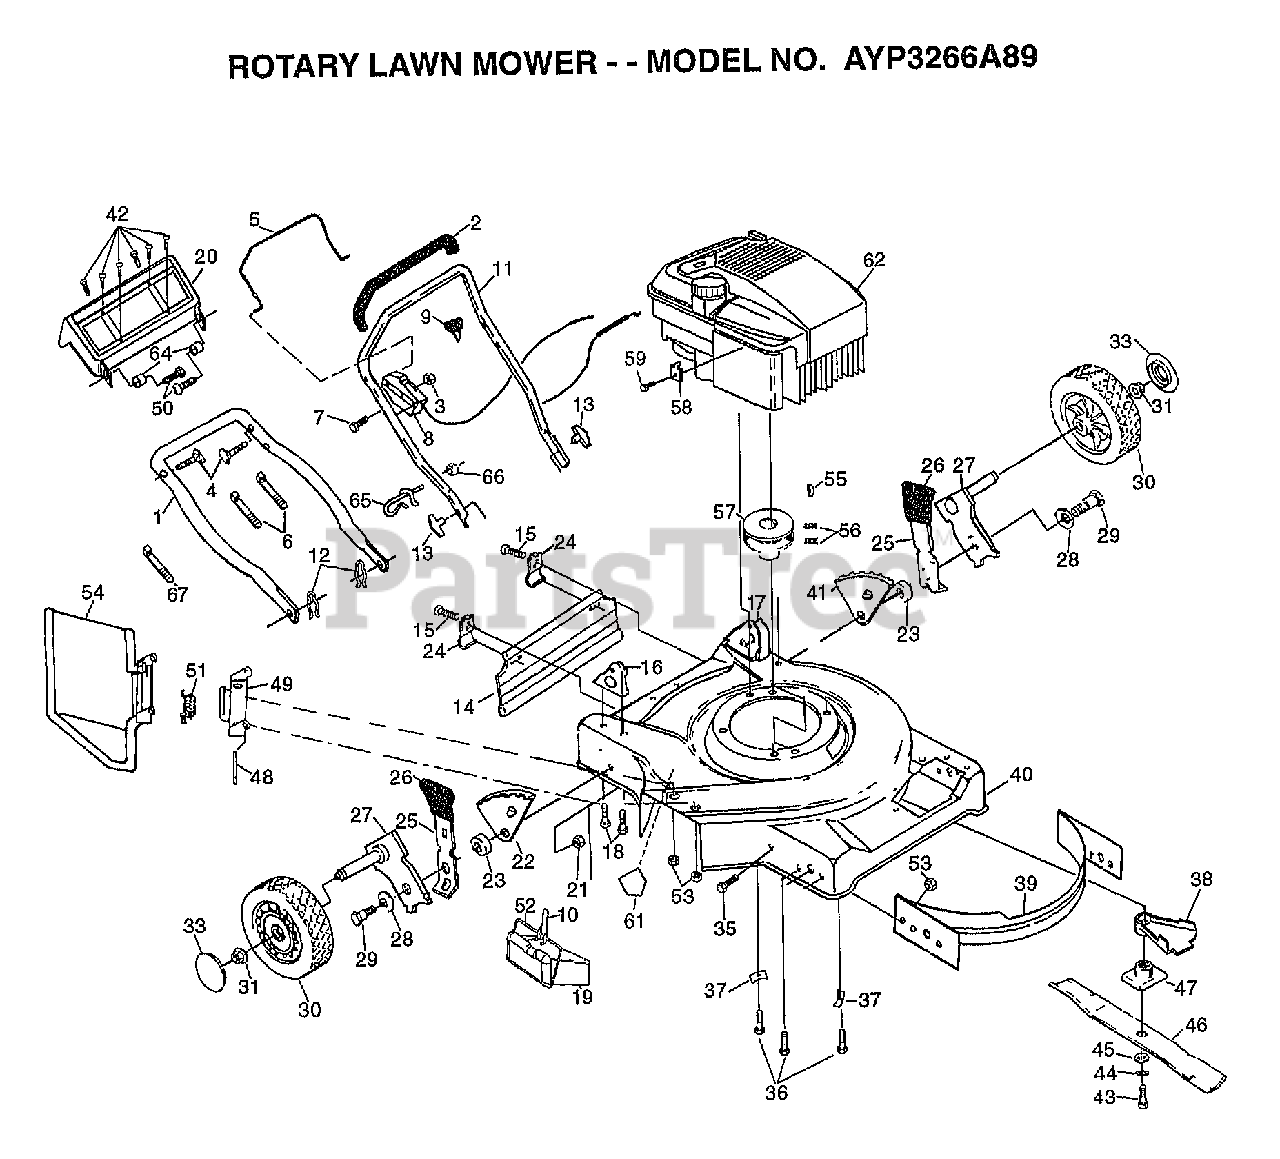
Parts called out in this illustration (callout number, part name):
3	LOCKNUT
4	BOLT.HANDLE.LM
5	BAIL.CNTRL.SRD.CM
7	SCREW.HXHD.WASH.
8	CONTROL.COMBI-KEY
9	KEY
10	LATCH.BAIL.MULCH.
12	HAIRPIN COTTER
13	KNOB HANDLE
14	SKIRT.REAR.FGD.22
15	TAPPING SCREW
16	HDLE BRKT ASSY.RH
17	HDLE BRKT ASSY LH
18	SCREW 5/16-18X3/4
19	MULCHER BAIL
21	LOCKNUT PM
23	SPACER.HEIGHT.ADJ
24	"BRKT,DEFL PM"
25	SELECTOR SPRING
27	ARM.AXLE.BZP.7POS
28	"WASHER, BELLEVIL."
29	BOLT SHLD 3/8-16
30	WHEEL.8X2.PR.RAD.
31	HEX FLANGE LOCKNT
33	HUB CAP
35	SCREW
36	BOLT.ENG.3/8-16
39	BAFFLE FRONT 22SD
40	MOWER HOUSING KIT
42	SCREW SELF TAP
43	SCREW
44	LOCKWASHER
45	"WASHER,HARDEN"
46	"BLADE.MULCH.22"""
47	ADAPTOR.BLADE.LM
48	ROD.HINGE.COMBI-C
49	BRACKET.HINGE.W/F
50	SCREW
51	SPRING.HINGE
52	MULCHER PLUG
54	GUARD.DISCH.22SD.
55	HI PRO KEY PM
56	SCREW
57	ENGINE.PULLEY.FWG
58	CABLE CLAMP
59	SCREW PM
61	DECAL-DANGER PM
64	NYLON BUSHING PM
65	ROPE GUIDE
